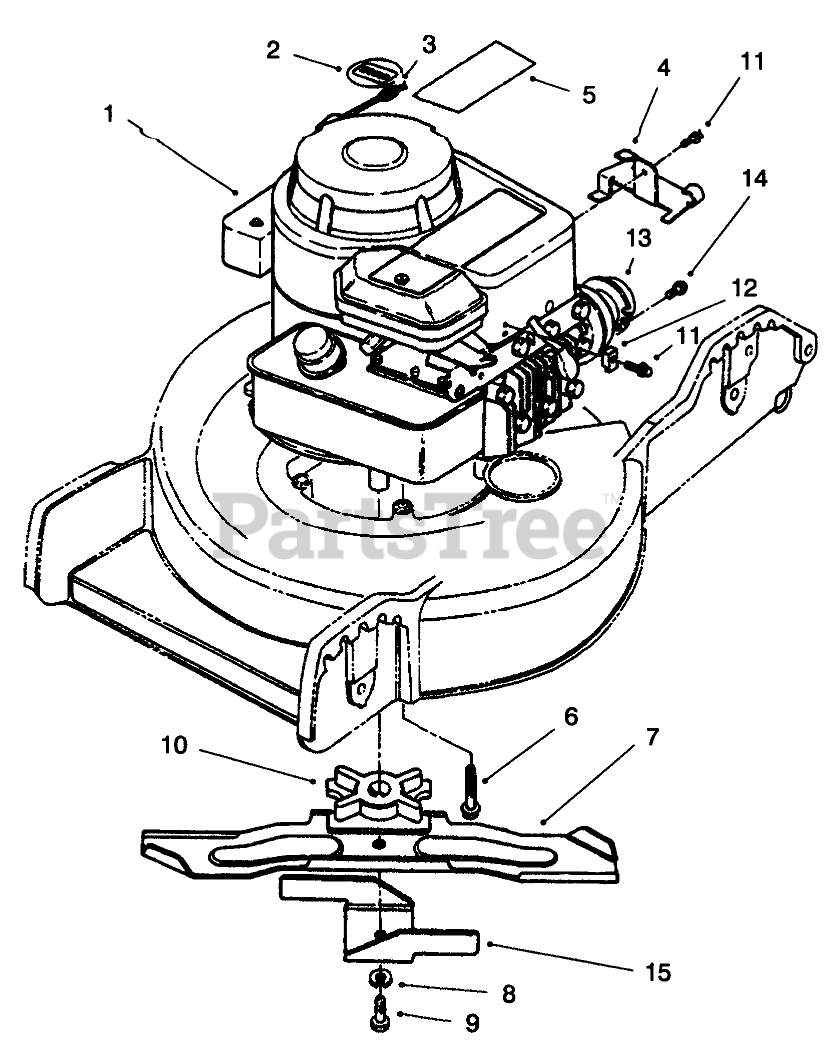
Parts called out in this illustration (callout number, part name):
2	DECAL - ENGINE
3	STOP-ROPE
4	CABLE BRACKET
5	DECAL - ENGINE
6	3/8-16X2 TAPTITE HEX HD
7	Blade-18"
8	WASHER-LOCK
9	SCREW-HH
10	BLADE RETAINER
11	CLAMP SCREW F/W ENGINE
12	CASING CLAMP F/W ENGINE
13	MUFFLER DEFLECTOR F/W
14	SCREW W/ENGINE
15	18 ACCELERATOR
